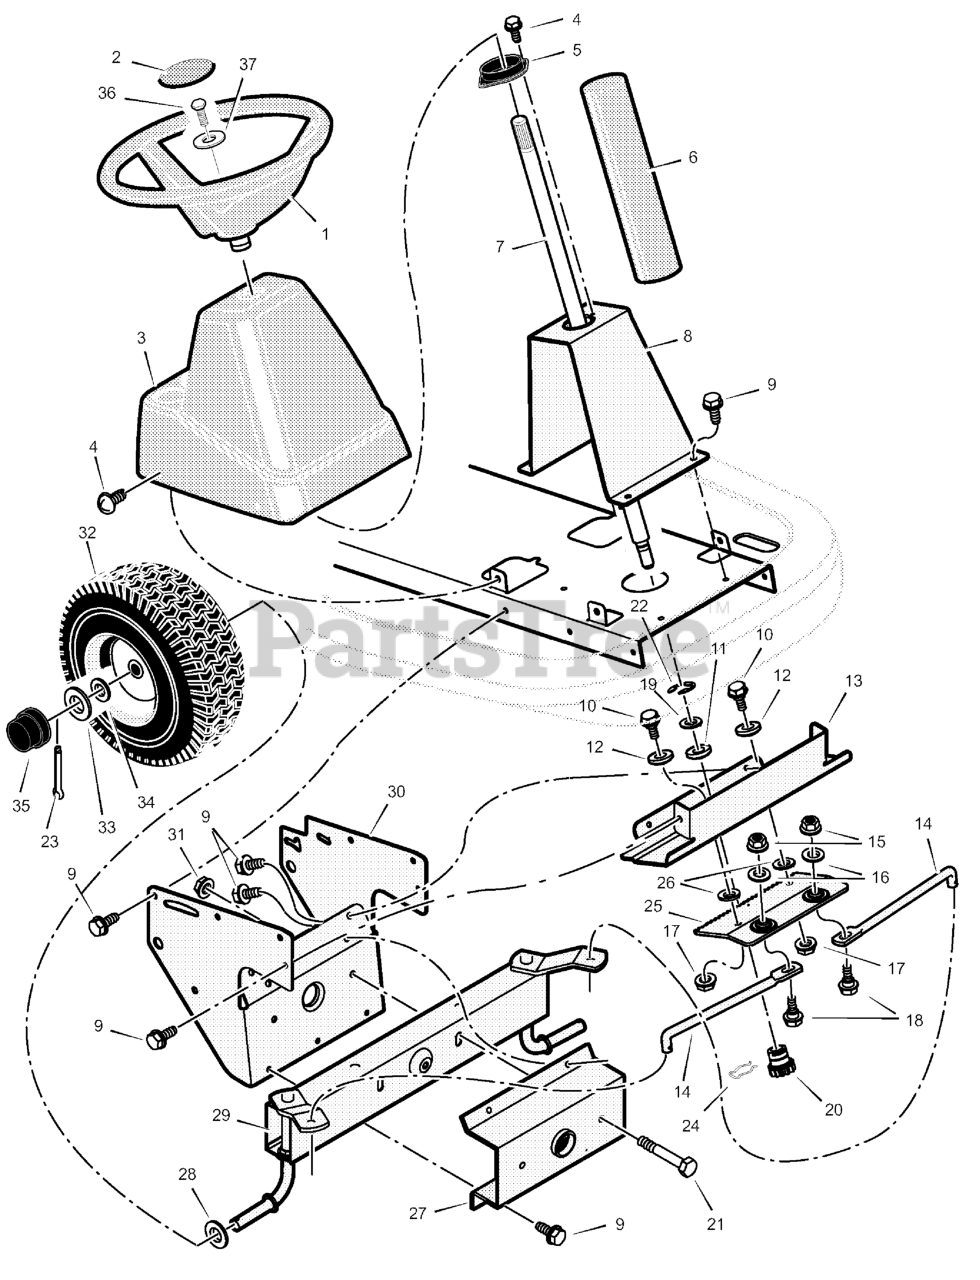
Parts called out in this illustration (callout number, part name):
1	Wheel, Steering (Black)
2	Insert, Steering
3	Console, Low (Black)
4	Screw
5	Bearing, Upper Steering
6	Tube, Steering (Black)
7	Shaft, Steering
8	Support, Steering
10	Bolt, Shoulder
11	Bearing, Lower Steering
13	Plate, Gear Mounting
14	Link, Drag
15	Nut, Flange
16	Washer
17	Nut, Flange
18	Bolt, Hex
19	WASHER, 1-1.3 16G FLT
20	Gear, Pinion
21	Bolt, Hex
22	E-Ring, Retainer
23	Pin, Cotter
24	Retainer, Spring
25	Rack, Steering
27	Bracket, Axle Front
28	Washer
29	Axle & Spindle Assembly
30	Bracket, Support
31	Nut, Flange
32	Wheel, Front *
34	Washer
35	Cap, Hub
36	Screw, Hex
37	Washer
